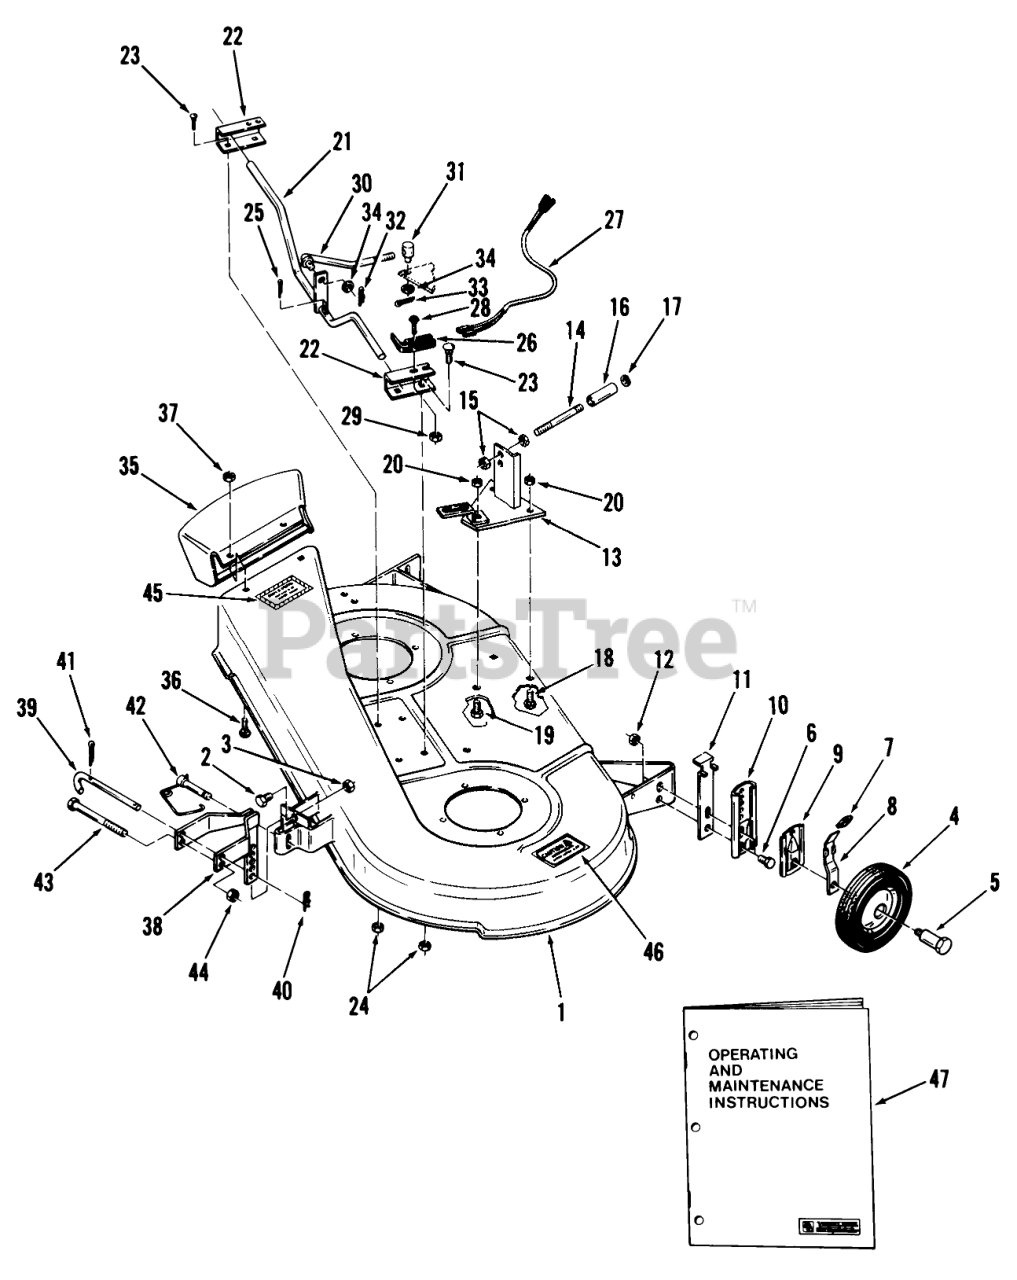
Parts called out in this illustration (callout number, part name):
1	Mower Deck for 95-32MS01
1	Mower Deck for 95-32XS01
1	Spindle Assembly (includes parts 2, 3, 4, 5, 6, 7, & 8)
2	BOLT
3	Nut
4	Wheel 6 X 1.25
5	BOLT-SHOULDER
6	Bolt-Special
7	HT ADJ TIP RED VINYL
8	HT ADJ SPRING LEVER
9	HT ADJ SLIDE
10	HT ADJ BACK PLATE
11	SAFETY-STOP& LIFT
12	Nut
13	Rear Hanger Support
14	ROD-HANGER
15	Eslok Nut
16	SPACER
17	Snap Ring
18	Bolt-Carriage
19	BOLT
20	Nut
21	Belt Stop Rod for 95-32MS01
21	Belt Stop Rod for 95-32XS01
22	Bracket
23	CARRIAGE BOLT -4
24	Nut
25	Cotter Pin
26	SWITCH
27	Wiring Harness
28	Fillister Hd. Screw #8-32 x 1
29	Hex Nut
30	Adjustment Rod
31	TRUNNION
32	Hairpin
34	Washer
35	ASSY-CHUTE EXT R
36	CARRIAGE BOLT -4
37	Nut
38	Front Hanger
39	"J" Pin
40	Hairpin
41	Cotter Pin
42	PIN-LOCKING
43	H H C S
44	Nut
45	Decal-Caution
46	Caution Decal
47	Owners Manual (Alternate 810108R1)
47	Operating and Maintenance Instructions for 95-32XS01
